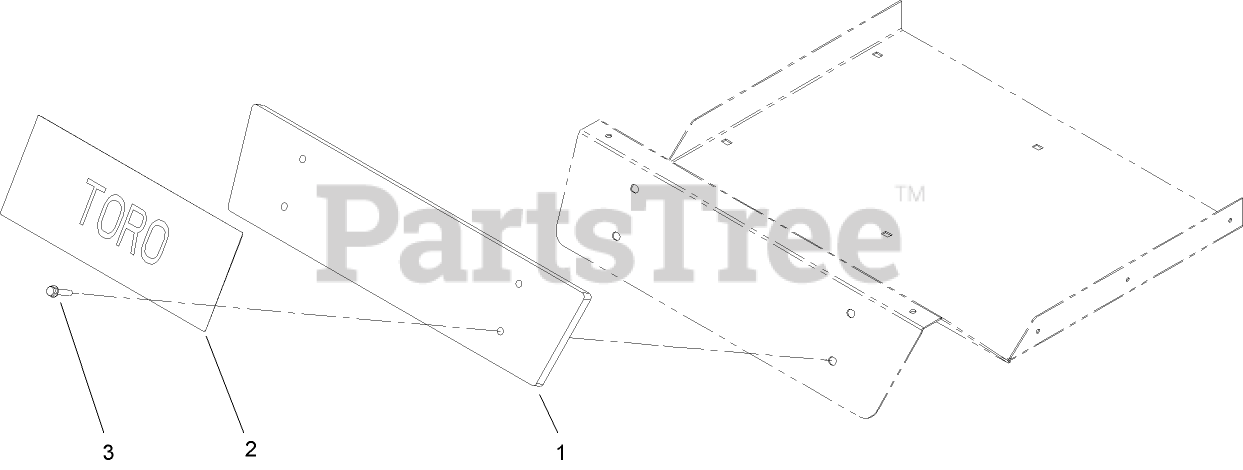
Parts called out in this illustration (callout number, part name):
1	WEIGHT-BAGGER
2	DECAL
3	SCREW-HHF
